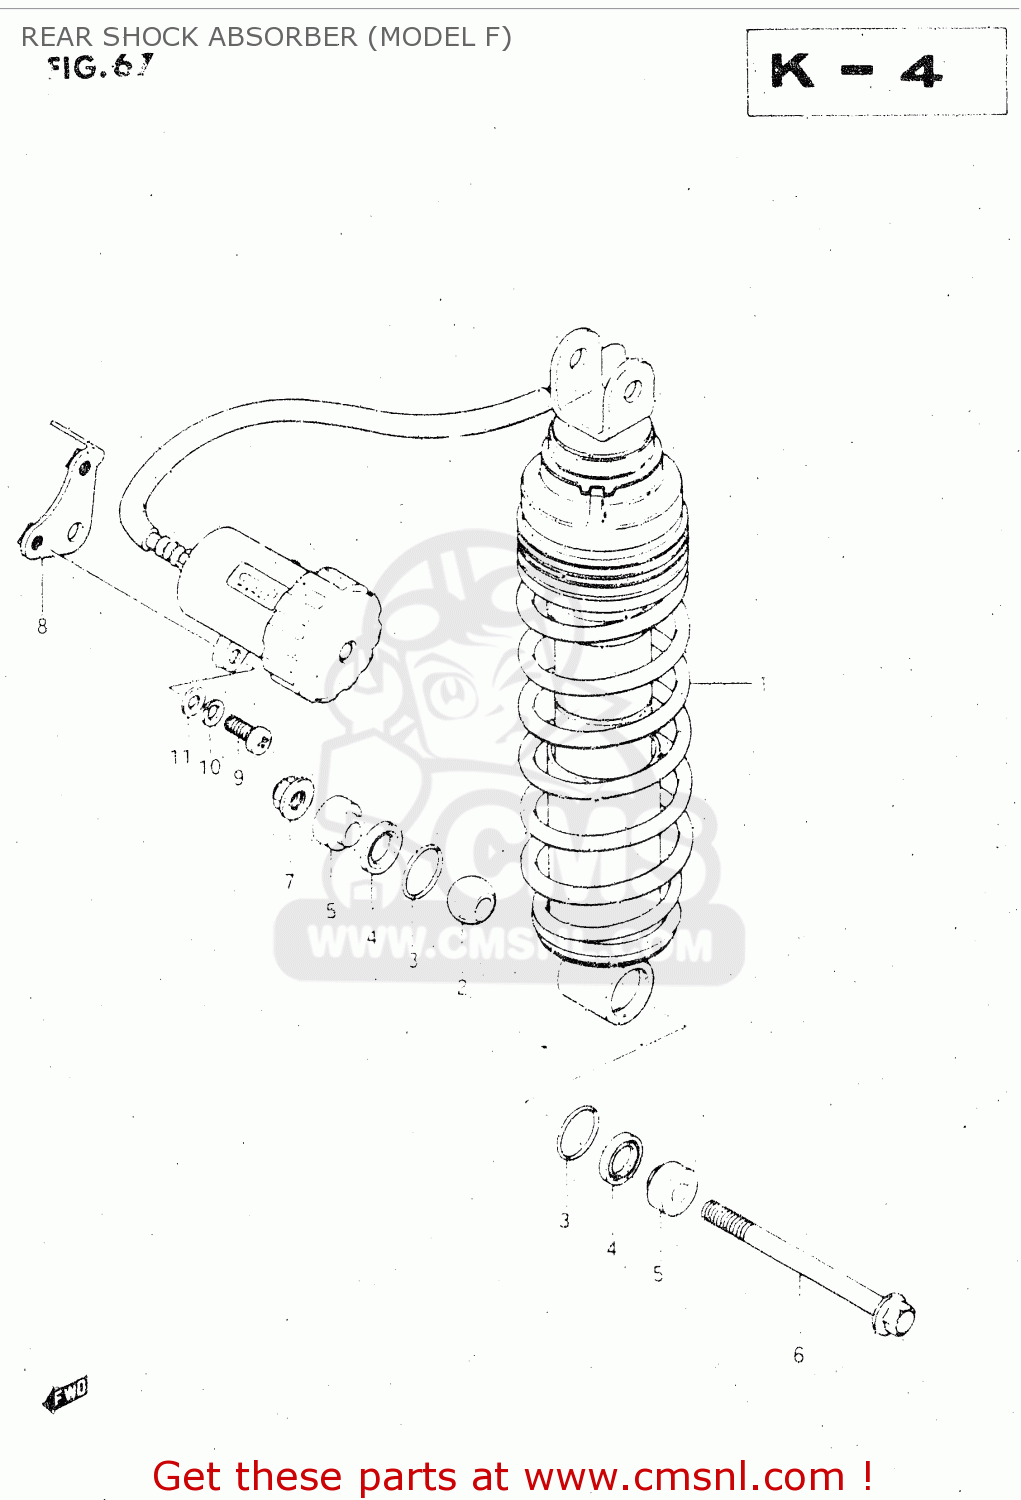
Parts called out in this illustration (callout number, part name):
1	SHOCK ABSORBER, REAR
2	BEARING,REAR SHOCK ABSORBER
3	RING
4	SEAL,DUST
5	COLLAR
6	BOLT(10X115)
7	NUT
8	BRACKET,RESERVOIR TANK
9	SCREW
10	WASHER,LOCK
11	WASHER
